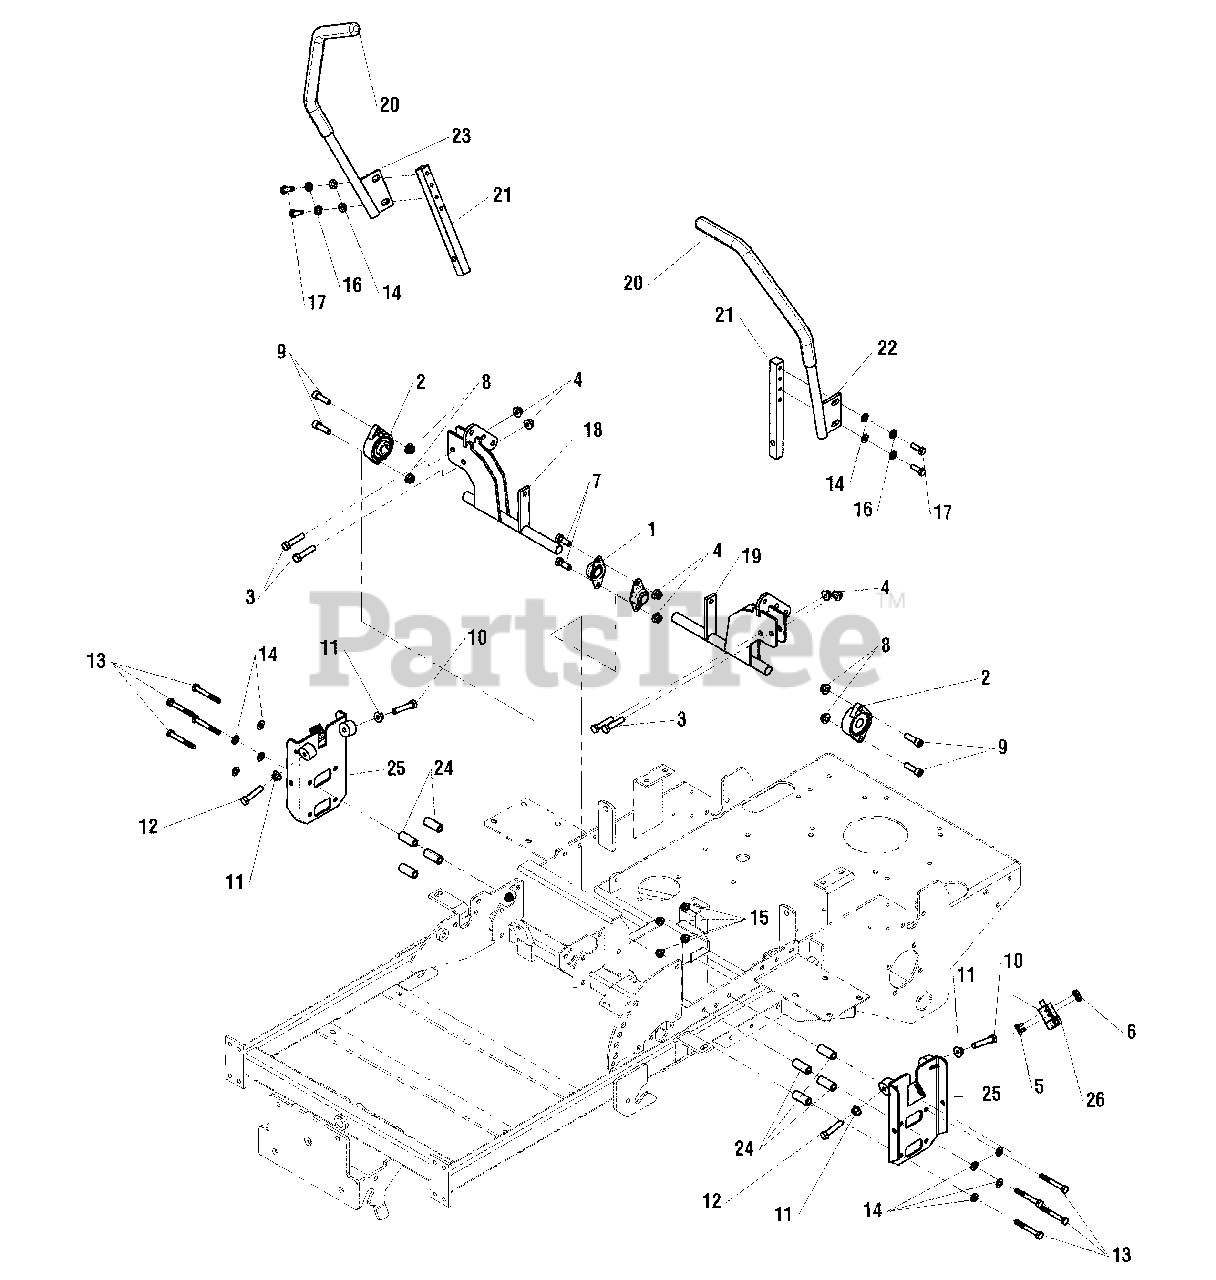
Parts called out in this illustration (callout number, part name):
1	BEARING, BRONZE FLANGE, 3/4"
2	BEARING, FLANGE
3	BOLT, 3/8-16 X 1-3/4" GD5 CZ
4	NUT, 3/8-16 HEX NYLOCK FLANGE
5	10-24 X .5 SCREW
6	NUT, HEX, #10-24
7	BOLT, 3/8-16 X 1" GD5 CZ
8	NUT, 3/8-16 HEX NYLON LOCK
9	3/8-16 x 1-1/4 SOCKET HD CAPSCR
10	BOLT, 5/16-18 X 2" GD 5 TFL
11	NUT, 5/16-18 HEX LG SERR FLG.
12	BOLT, 5/16-18 X 1.75" GD 5 TFL
13	BOLT, 5/16-18 X 2-1/2" GD5
14	WASHER, 5/16" SAE
15	NUT, 5/16-18 HEX NYLOCK FLANGE
16	WASHER, 5/16" LOCK
17	BOLT, 5/16-18 X 1" GD5
18	WELD, CONTROL SHAFT- RH
19	WELD, CONTROL SHAFT- LH
20	GRIP, FOAM, 3/4" ID, 16" LONG
21	MOUNT, CONTROL ARM
22	WELD, HANDLE MOTION CONTROL-LH
23	WELD, HANDLE MOTION CONTROL-RH
24	SPACER, .63 X .39 X 1.50
25	WELD, NEUTRAL PLATE
26	SWITCH, PLUNGER, N.O. / N.C.
